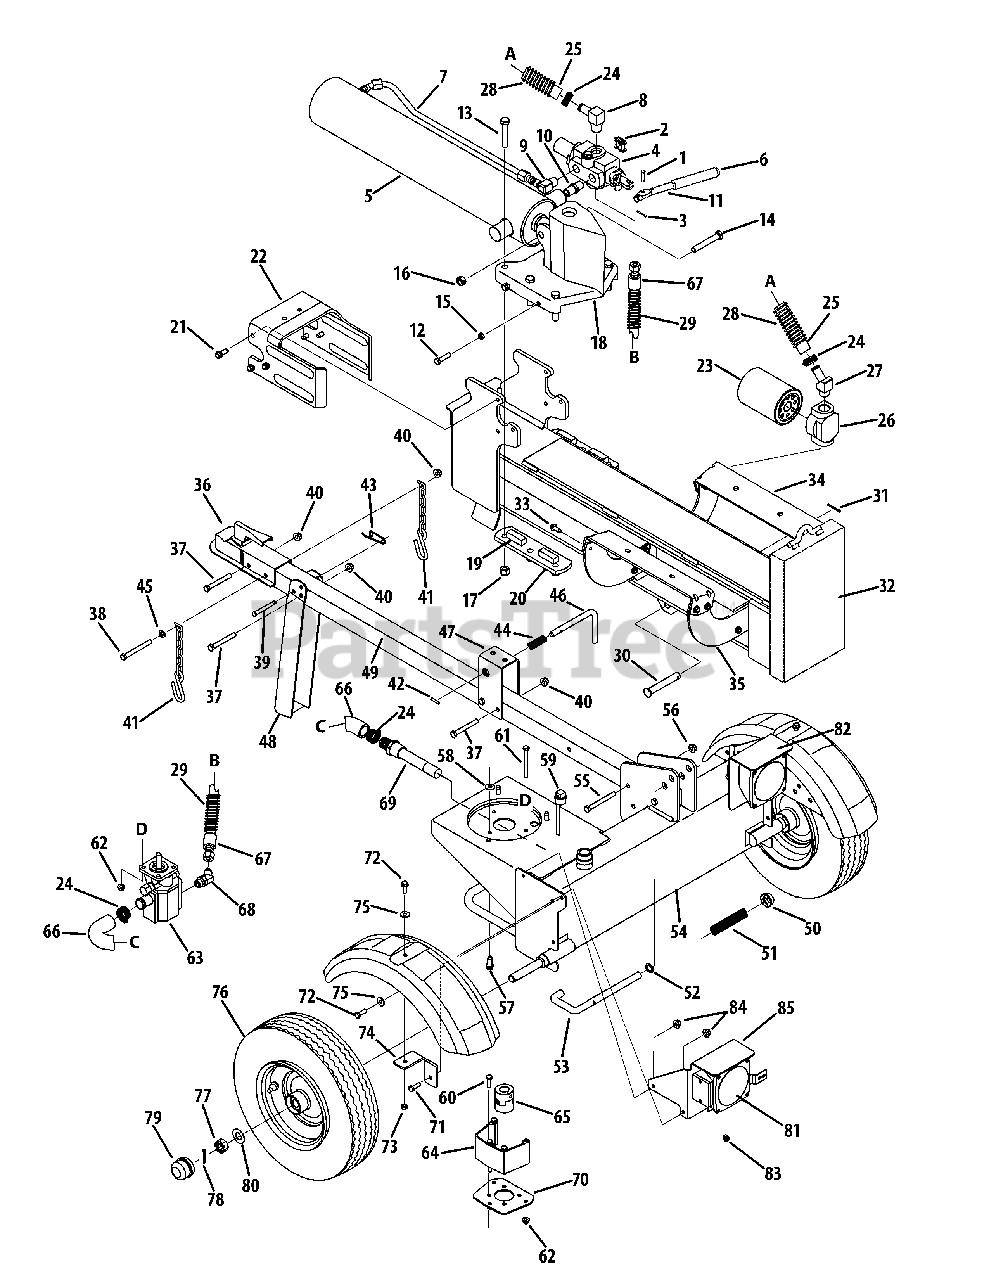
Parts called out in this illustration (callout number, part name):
1	Clevis Pin, .25 x 1.00
2	Handle Valve Link
3	Cotter Pin, 3.322 x 1.0
4	Valve (Model 510)
4	Valve (Model 550)
4	Valve (Model 570)
5	Hydraulic Cylinder
7	Hydraulic Hose, 3.4-16
8	Hydro Fitting, 90 x 3.4 x .75
9	Hydro Fitting, 90 x 3.4 x 1/2
10	Nipple Fitting, 1.2 x 1.89
11	Hydraulic Valve Control
12	Hex Screw, 3.8-24 x 1.50
13	Hex Screw, 1.2-20 x 2.75
14	Hex Screw, 1.2-13 x 3.25
15	Jam Nut, 3.8-24
16	Hex Lock Nut, 1.2-13
17	Hex Lock Nut, 1.2-20
20	Back Plate
21	Self-Tapping Screw, 3.8-16-1.000
22	Dislodger Bracket - Gray
22	Dislodger Bracket - Red
23	Oil Filter
24	Hose Clamp
25	Return Hose
26	Filter Housing
27	Adapter, 3.4-14
28	Hose Guard (510/570)
29	Hose Guard (510/570)
30	Clevis Pin, .625 x 4.0
31	Cotter Pin, 1.8 x 1.25
32	Beam Assembly
33	Hex Washer Screw, 5.16-18 x .750
34	Log Tray Bracket
35	Log Tray Bracket
36	Hitch Coupling Assembly
37	Hex Screw, 3.8-16 x 3.00
38	Hex Screw, 3.86 x 3.50
39	Clevis Pin, 5.16 x 2.5
40	Flange Lock Nut, 3.8-16
41	Tow Chain
42	Spirol Pin, 3.16 x 1.00
43	Spring Pin
44	Compression Spring, .66 x 1.8
45	Flat Washer, .375 x .738 x .063
46	Tongue Latch Rod
47	Tongue Latch - Gray
47	Tongue Latch - Red
48	Jack Stand
49	Tongue Tube - Gray
49	Tongue Tube - Red
50	Push Cap, 5.8
51	Compression Spring, .625 x 4.0
52	Flat Washer, .635 x .93 x .06
53	Lock Rod
54	Frame Assembly
55	Hex Screw, 3.8-16 x 3.50
56	Flange Lock Nut, 3.8-16
57	Self-Tapping Screw, 3.8-16 x 1.250
58	Flat Washer, .407 x .812 x .135
59	Vented Dipstick
60	Hex Screw, 5.16-18 x 1.00
61	Hex Screw, 5.16-18 x 3.25
62	Flange Lock Nut, 5.16-18
63	Gear Pump
64	Coupling Shield
65	Flex Coupling
65	Set Screw, 1.4-20 x .38
65	Square Key, 3.16 x .75
65	Coupling, .500
65	Coupling, .875
65	Spider Bushing
66	Inlet Hose
67	Rubber Hydro Hose
68	Hydraulic Fitting, 45 x 3.4 x 3.4
69	Inlet Filter
70	Rear Coupling Support Bracket
71	Hex Washer Screw, 5.16-18 x 1.000
72	Hex Washer Screw, 5.16-18 x .875
73	Flange Lock Nut, 5.16-18
74	Fender (Black, 510/570)
74	Fender (Red, 550)
75	Flat Washer, .343 x .880 x .062
76	Complete Wheel Assembly
77	Slotted Nut, 3/4-16
78	Cotter Pin, 5.32 x 1.25
79	Hub Cap
80	Flat Washer, .760 x 1.50 x .030
81	Light Assembly Kit (570)
82	LH Light Bracket (570)
83	Jam Nut, 3.8-16 (570)
84	Flange Lock Nut, 5.16-18 (570)
85	RH Light Bracket (570)
